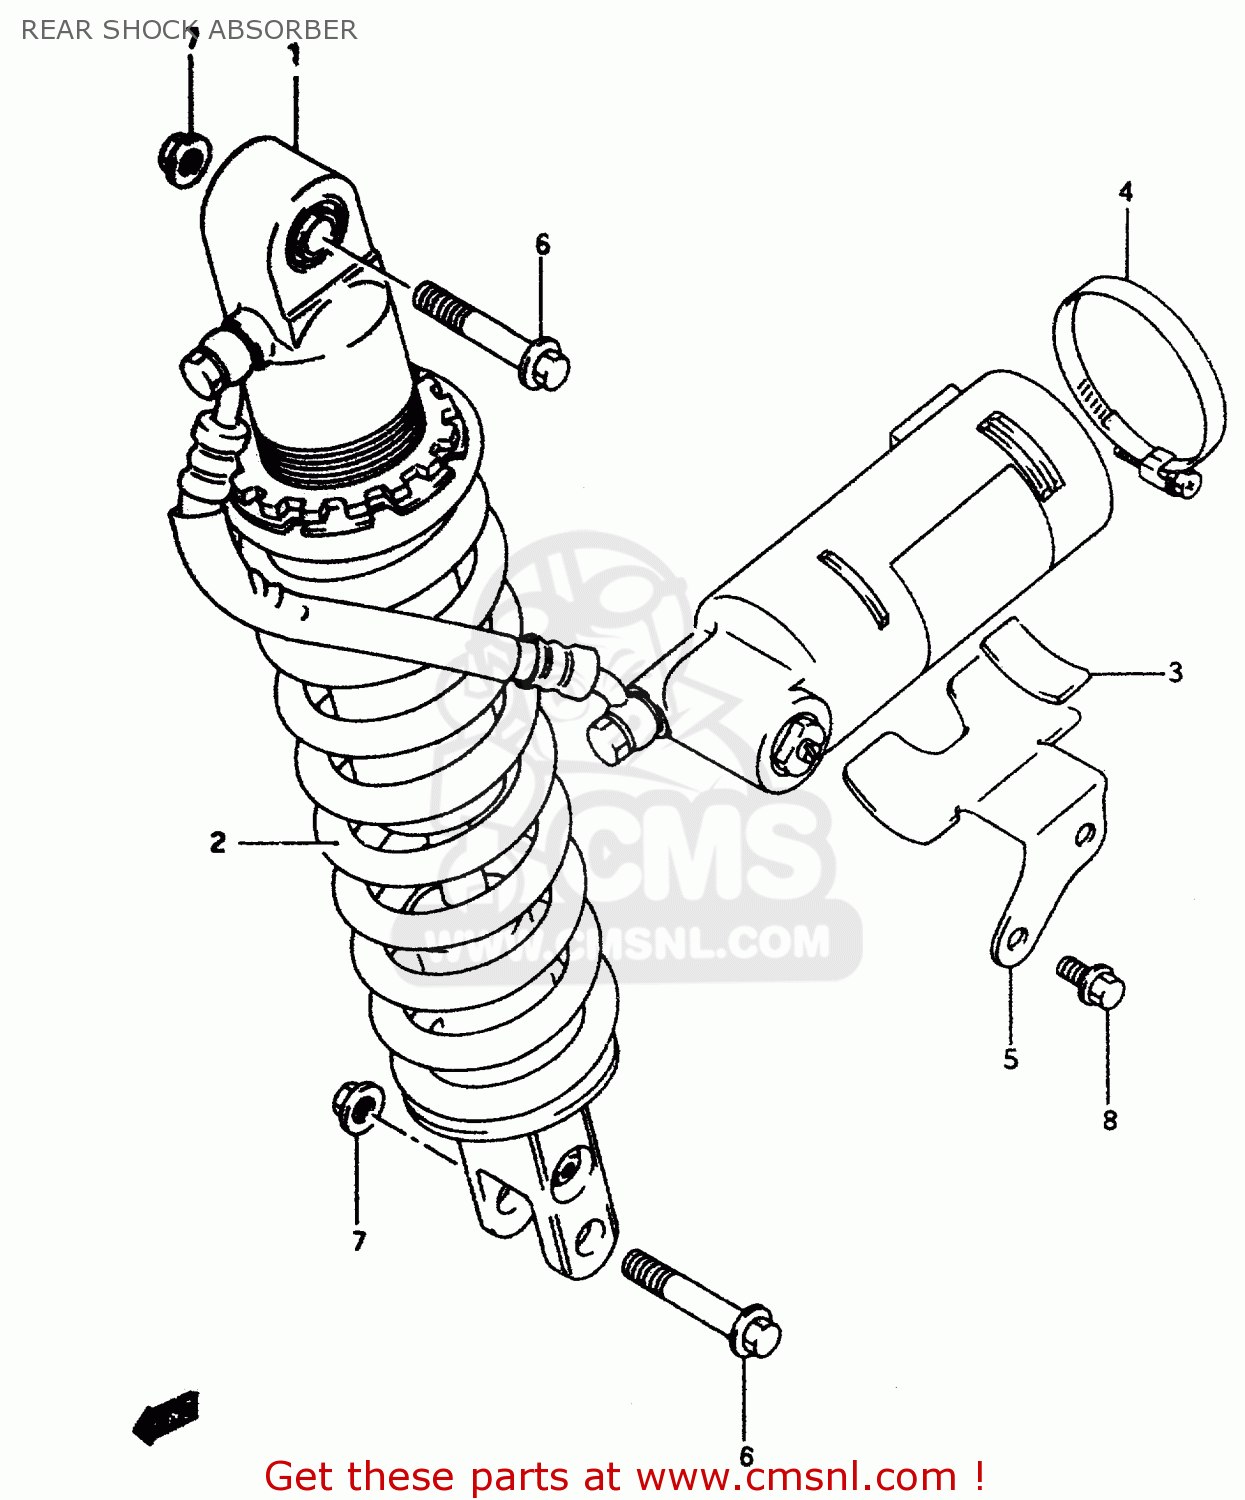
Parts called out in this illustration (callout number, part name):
1	ABSORBER ASSEMBLY,REAR SHOCK
2	SPRING
3	CUSHION
4	CLAMP
5	BRACKET,RESERVOIR TANK
6	BOLT,RR SHOCK ABSORBER
7	NUT
8	BOLT
